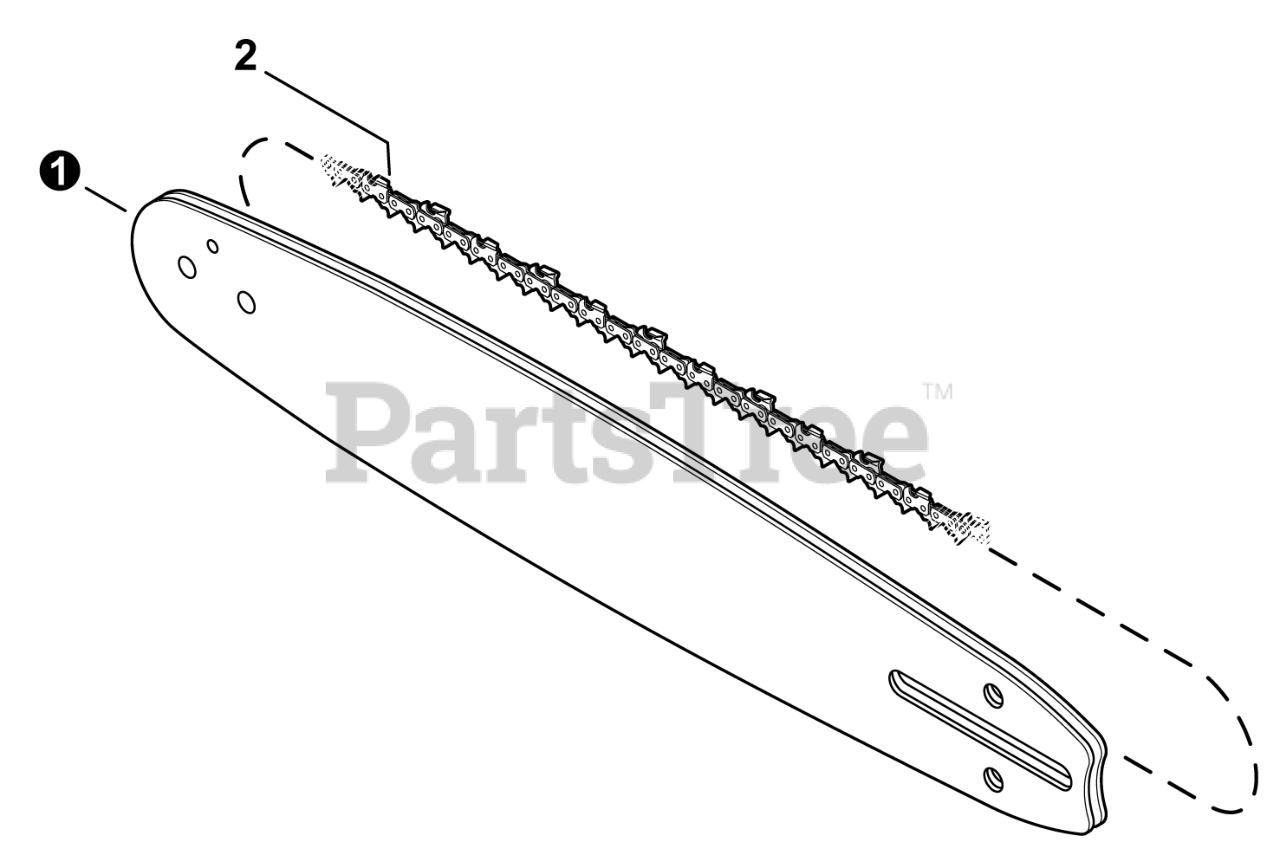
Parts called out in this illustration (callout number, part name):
1	GUIDE BAR, 18" PRO-LITE
1	GUIDE BAR, 20" PRO-LITE
1	GUIDE BAR, 24" PRO-LITE
1	GUIDE BAR, 18" ARMOR TIP
1	GUIDE BAR, 20" ARMOR TIP
1	GUIDE BAR, 24" ARMOR TIP
1	GUIDE BAR, 28" ARMOR TIP
2	SAW CHAIN 18"
2	SAW CHAIN 20"
2	SAW CHAIN 24"
2	SAW CHAIN 28"
